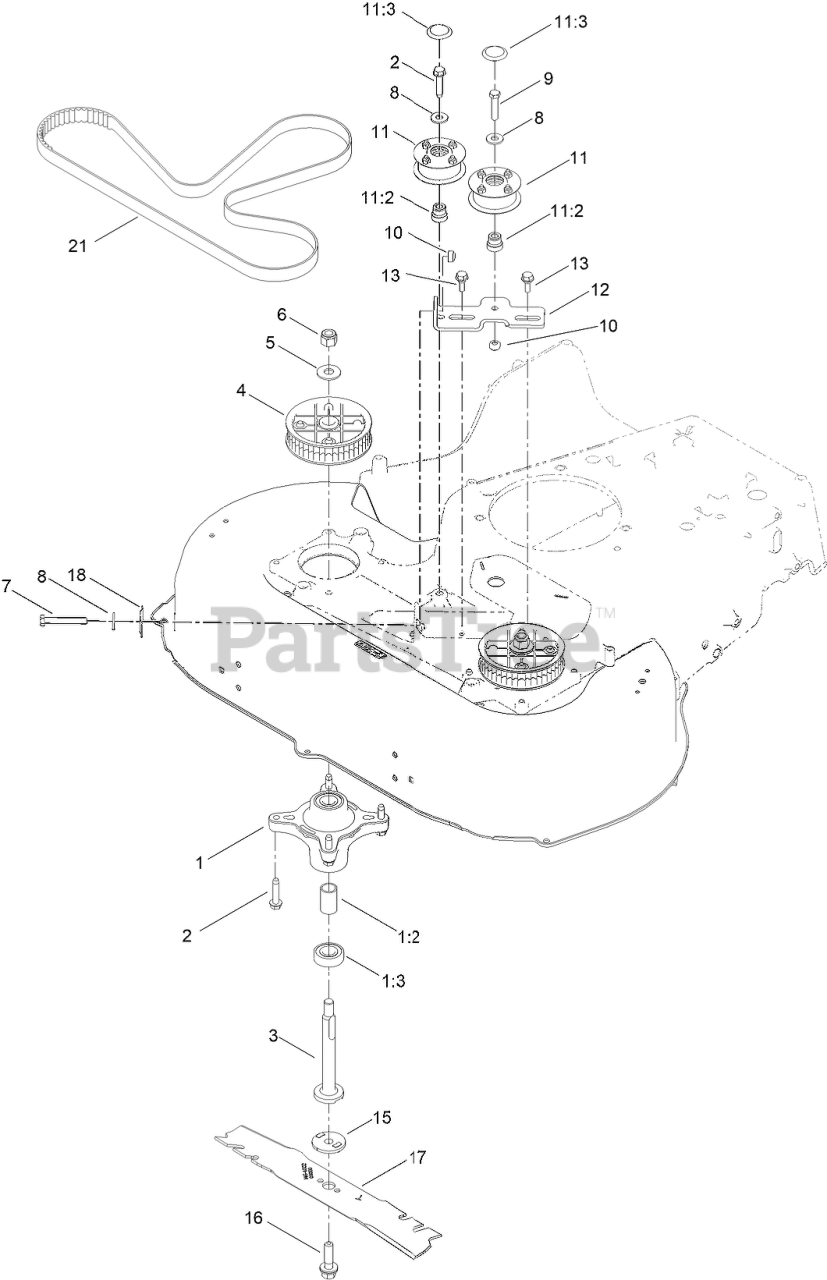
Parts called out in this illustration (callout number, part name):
1	SPINDLE ASM
1:2	SPACER
1:3	BEARING-BALL
2	SCREW-THD ROLL, HWH
3	SHAFT-SPINDLE
4	SPROCKET
5	WASHER-SPRING
6	NUT-HEX
7	BOLT-HH FT
8	WASHER-FLAT
9	SCREW-HH
10	NUT-LOCK, NI
11	PULLEY KIT
11:2	ADAPTER-BORE
11:3	PLUG-CAP
12	BRACKET-IDLER
15	ADAPTER-BLADE
16	BOLT-BLADE
17	BLADE-ROTARY [BLACK]
18	SPRING-FLAT
21	BELT-SYNCHRONOUS
